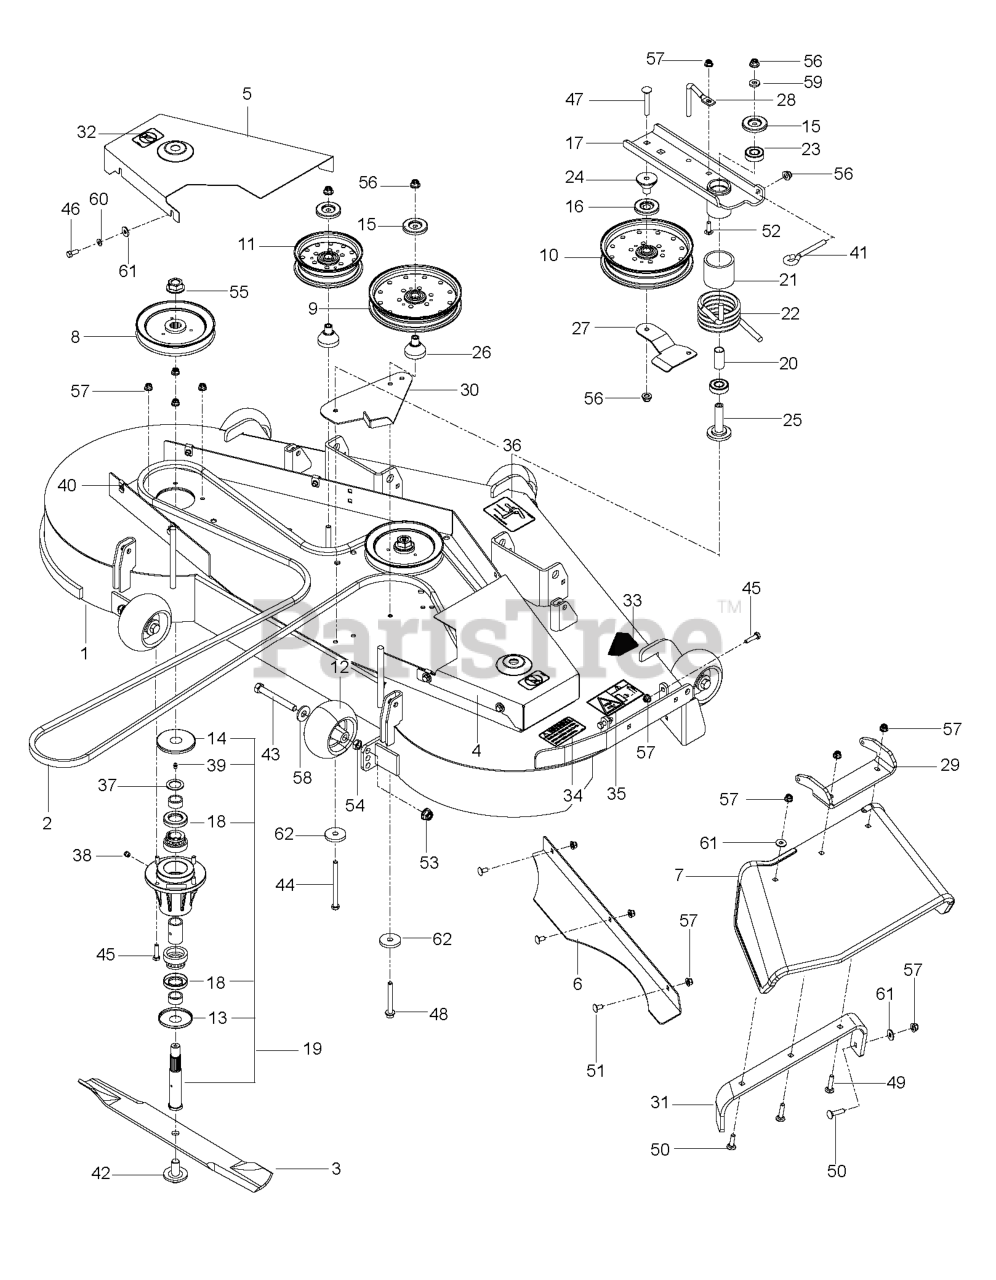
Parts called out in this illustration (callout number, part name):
1	DECK.SVC.W/DECALS.61.PZT.ORNGE
3	BLADE - HEAVY DUTY 21"
4	SHIELD BELT RH 61" ORANGE
5	SHIELD BELT LH 61" ORANGE
6	CONFINEMENT PLATE 61
7	CHUTE, RUBBER DISCHARGE 52/61"
8	PULLEY, 61
9	PULLEY - IDLER 7"
10	PULLEY - 7" NARROW
11	IDLER PULLEY
12	GAUGE WHEEL
13	BOTTOM DUST CAP
14	TOP DUST CAP
15	DUST SHIELD
16	SHIELD, DUST
17	IDLER.ARM.BLACK
18	SHAFT SEAL
19	HOUSING ASM, 52/61
20	SPACER, IDLER BEARINGS
21	SPACER, IDLER PIVOT
22	SPRING, TORSION, IDLER
23	BEARING, BALL
24	BEARING, IDLER ARM
25	BEARING, IDLER PIVOT
26	BEARING, IDLER STANDOFF
27	BELT.GUIDE.BLACK
28	BELT KEEPER
29	PIVOT BRACKET - CHUTE
30	BRACKET, SPRING STOP
31	BRKT, REINF - CHUTE 52/61"
32	DECAL, NO STEP
33	DECAL, CPSC
34	DECAL, CAUTION
35	DECAL, EURO SEVERING
36	DECAL, BELT ROUTING
37	MACHINE BUSHING
38	PLUG-VENTED
40	U-CLIP 5/16-18 NUT RETAINER
41	EYE BOLT, 3/8 X 4"
42	BLADE BOLT/WASHER
43	HCS 1/2-13 X 4 GR 5 ZD
44	HCS 3/8-16 X 4-1/2 GR 8 ZD
45	HCS 5/16C X 1 1/4
46	HCS 5/16C X 3/4
47	CARRIAGE BOLT 3/8-16 X
48	HHFS 3/8-16 X 3 GRD 5 ZD
49	RHSNB 5/16-18 X 1-1/2 GR 5 ZD
50	BOLT, CARRIAGE 5/16X1-1/4
51	CARRIAGE BOLT 5/16C X 5/8"
52	RHSSNB 5/16C X 1.0
53	NUT, 1/2-13 HEX FLG NYLOC ZD
54	NUT 1/2 HEX JAM
55	NUT FLANGE 3/4-16
56	NUT 3/8-16 HEX FLG NYLOC ZD
57	5/16-18 NYLOC FLANGE NUT
58	WASH USS FLAT 1/2
59	WASHER, 3/8 THICK
60	WASH 5/16 DISC SPRING ZD
61	WASHER 5/16 FLAT
62	SPINDLE WASHER
